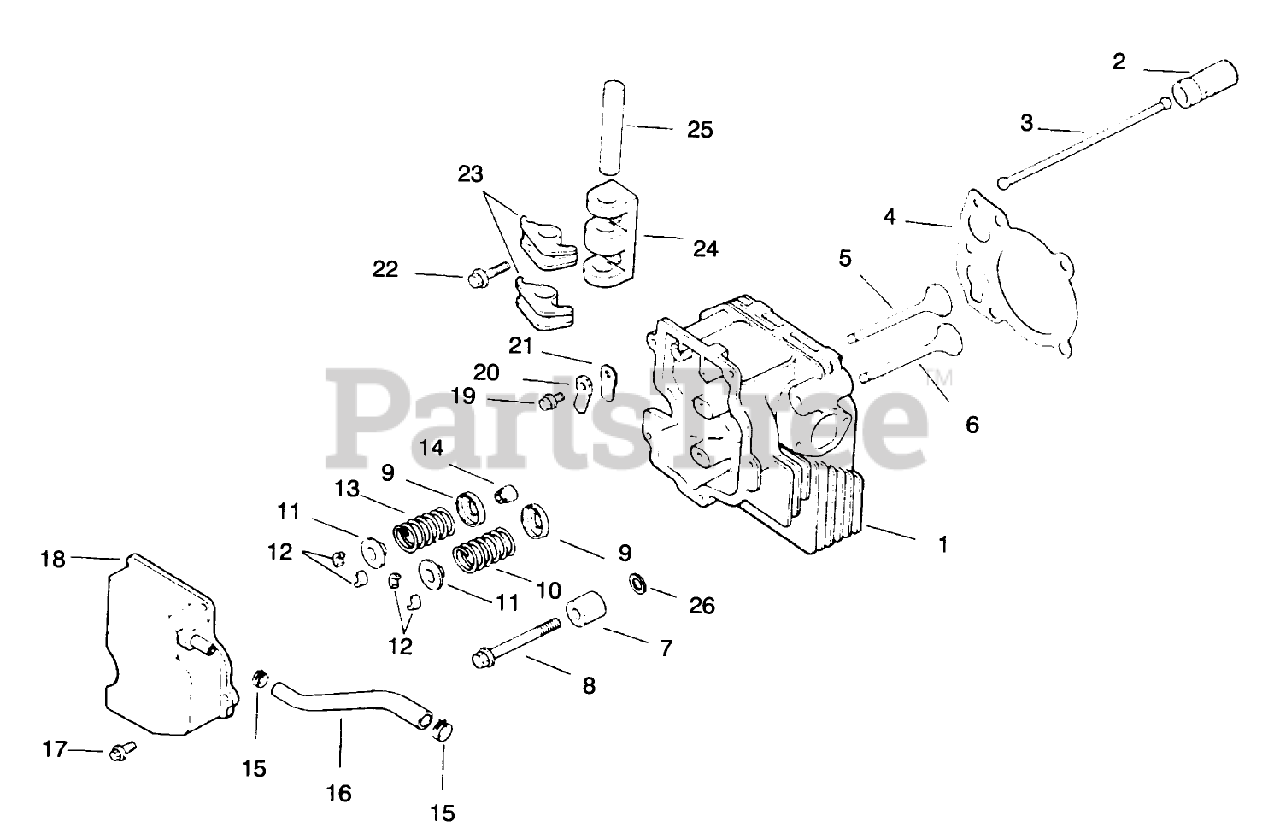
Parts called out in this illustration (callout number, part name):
1	Cylinder Head
2	Lifter-Valve
3	Rod-Push (Only On: 72042,72043,72062,72063)
4	Gasket-Cylinder Head (Only On: 72042, 72063, 72062, 72043)
5	Valve-Intake STD (Only On: 72042, 72063, 72062, 72043)
6	Valve-Exhaust STD (Only On: 72042,72043,72062,72063)
7	Spacer-Head Bolt Exhaust (Only On: 72042, 72063, 72062, 72043)
8	Screw M10x1.5x80 (Only On: 72042, 72063, 72062, 72043)
9	Retainer-Spring
10	Spring-Valve Intake (Only On: 72042, 72063, 72062, 72043)
11	Cap-Valve Spring
12	Kit-Retainer
13	Spring-Valve Exhaust (Only On: 72042,72043,72062,72063)
14	Seal
15	Clamp
16	Hose-Breather (Only On: 72042, 72063, 72062, 72043)
18	Cover-Valve W/Nipple (Only On: 72042, 72063, 72062, 72043)
20	Retainer-Reed
23	Arm-Rocker
24	Bridge-Rocker Arm
25	Shaft-Rocker Arm
26	Washer-Flat (Only On: 72042, 72063, 72062, 72043)
